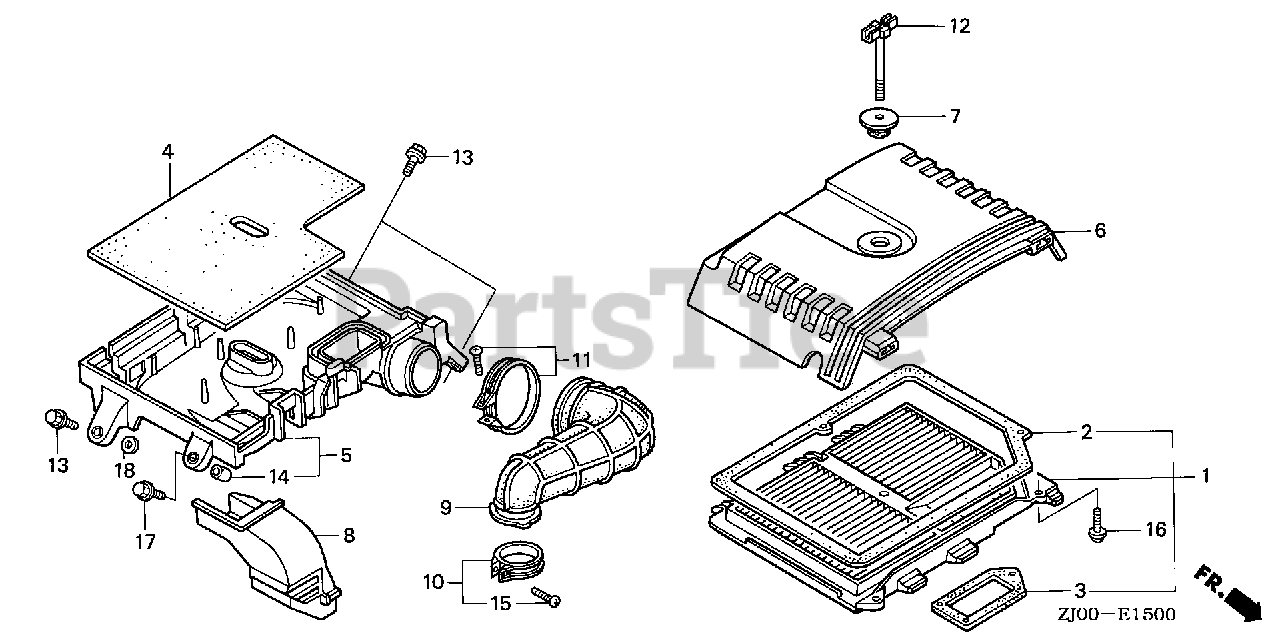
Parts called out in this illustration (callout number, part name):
1	ELEMENT SET, AIR CLEANER
2	GASKET A, ELEMENT
3	GASKET B, ELEMENT
4	FILTER (OUTER)
5	HOUSING, AIR CLEANER
6	COVER, AIR CLEANER
7	GROMMET, AIR CLEANER
8	HOSE, AIR CLEANER (NOT AVAILABLE)
9	TUBE, AIR CLEANER CONNECTING
10	BAND, AIR CLEANER CONNECTING TUBE
11	BAND, AIR CLEANER CONNECTING TUBE (50)
12	BOLT, AIR CLEANER
13	BOLT, FLANGE (6X23) (CT200)
14	COLLAR, AIR CLEANER HOUSING
15	SCREW, PAN (4X20)
16	SCREW-WASHER (5X16)
17	BOLT, FLANGE (6X18)
